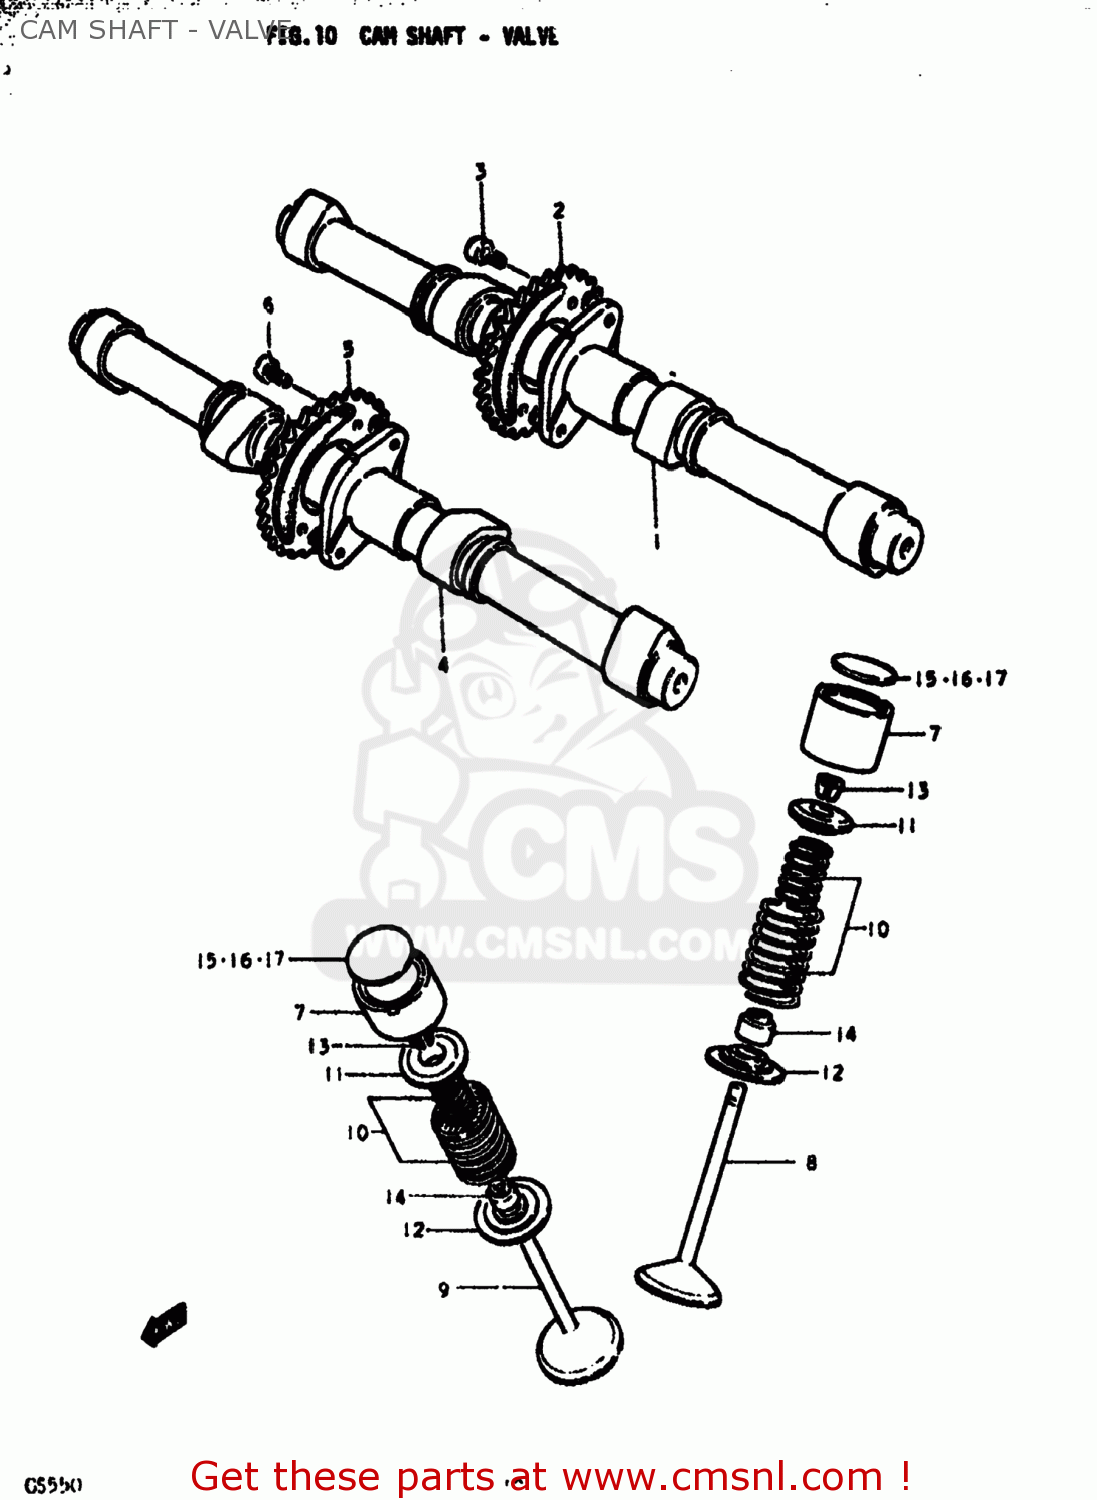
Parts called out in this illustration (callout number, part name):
1	CAMSHAFT
2	SPROCKET,CAMSHAFT
3	BOLT 6X11
4	CAMSHAFT,EXHAUST
5	SPROCKET,EXHAUST CAMSHAFT
6	BOLT 6X11
7	TAPPET
8	VALVE,INTAKE
9	VALVE,EXHAUST
10	SPRING SET,VALVE
11	RETAINER,VALVE SPRING
12	SEAT,VALVE SPRING
13	SHIM,TAPPET
14	SEAL,OIL(7X14.4X9)
15	SHIM,TAPPET
16	SHIM,TAPPET
17	SHIM,TAPPET
18	SHIM SET,TAPPET
19	CASE
